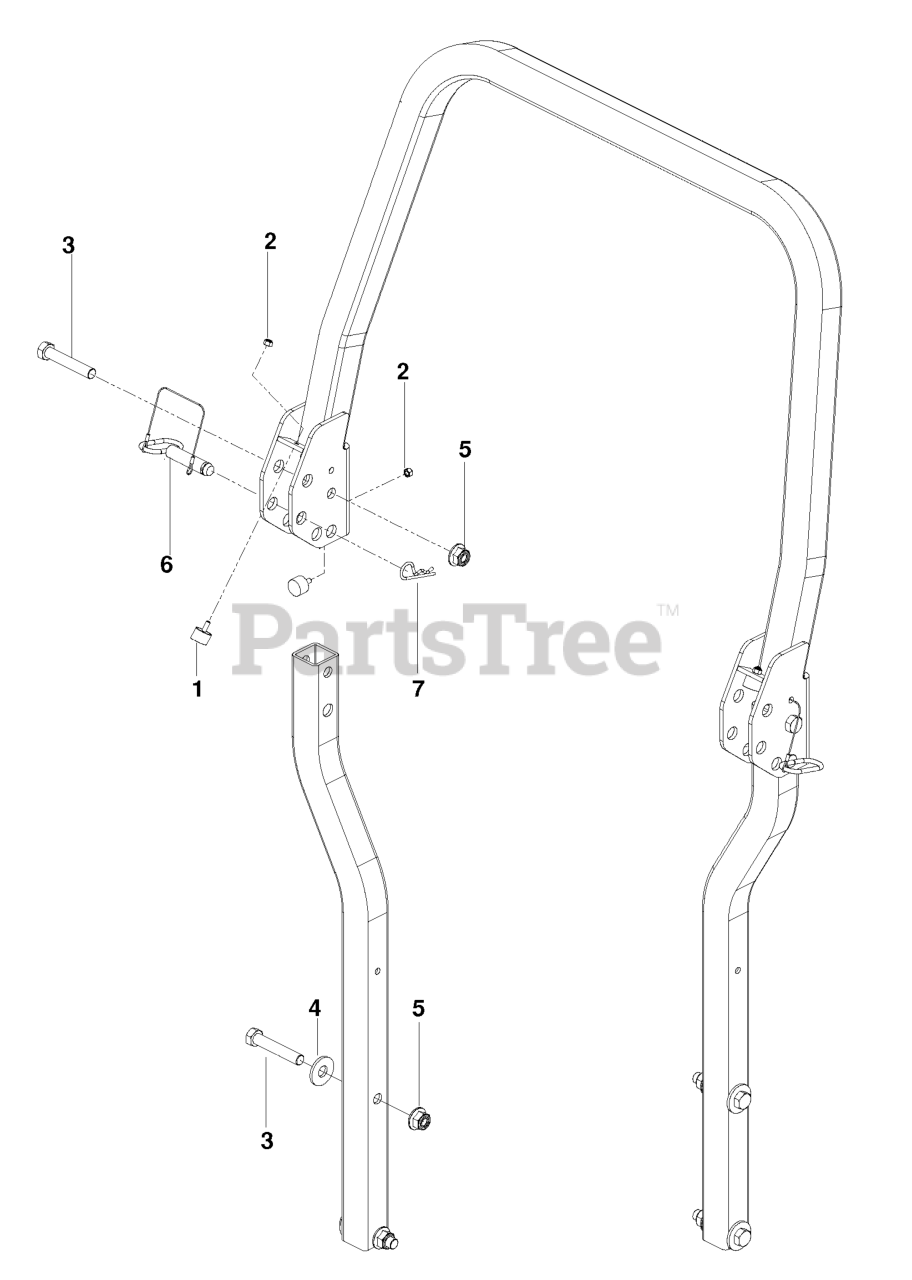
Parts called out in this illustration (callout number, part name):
1	BUMPER, MALE STUD, 1/4-20
2	NUT.1/4-20.HEX.NYLOC.ZD
3	5/8-11 X 3-1/2 HHB GRADE 5
4	WASHER, 5/8 FLAT
5	NUT 5/8-11 FLG NYLOC ZD
7	PIN HAIR .148 X 2-15/16 #210
